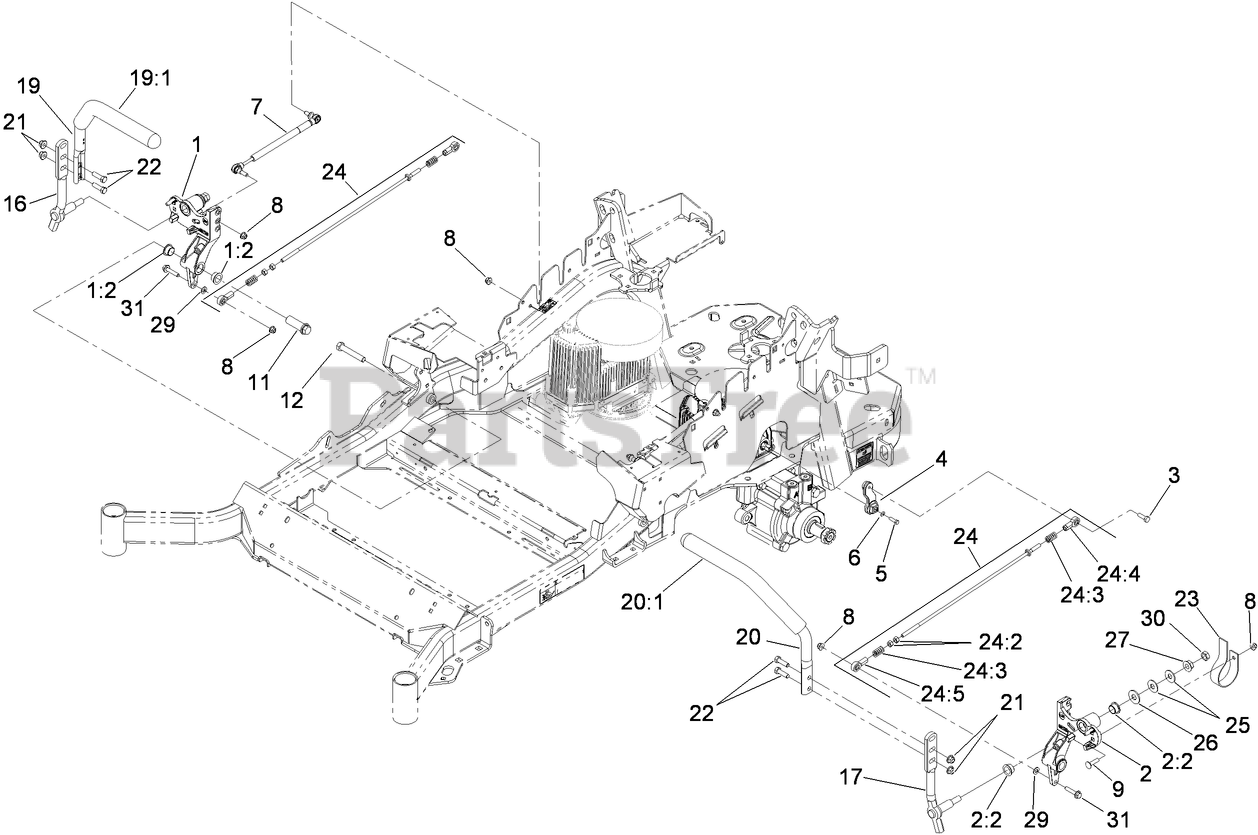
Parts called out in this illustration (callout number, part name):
1	RH MOTION CONTROL AND BUSHING ASM
1:2	BUSHING-FLANGE
2	LH MOTION CONTROL AND BUSHING ASM
2:2	BUSHING-FLANGE
3	SCREW-HH, THREAD LOCKING
4	ARM-CONTROL, PUMP
5	SCREW-HH
6	WASHER-SPRING
7	DAMPER-CONTROL, MOTION
8	NUT-HF, NI
9	BOLT-CARR
11	HUB-THREADED
12	SCREW-HH
16	LEVER-CONTROL MOTION, RH
17	LEVER-CONTROL MOTION, LH
19	RH STEERING HANDLE ASM
19:1	Grip-Control, Motion
20	LH STEERING HANDLE ASM
20:1	Grip-Control, Motion
21	NUT-HF, NI
22	SCREW-HH
23	SPRING-LEAF
24	FRONT PUMP LINKAGE ASM
24:2	NUT-HEX
24:3	SPRING-COMPRESSION
24:4	BALLJOINT-LH
24:5	BALLJOINT-RH
25	WASHER-SPRING
26	WASHER-FLAT
27	NUT-HF
29	WASHER-PLAIN
30	NUT-JAM
31	SCREW-HHF
